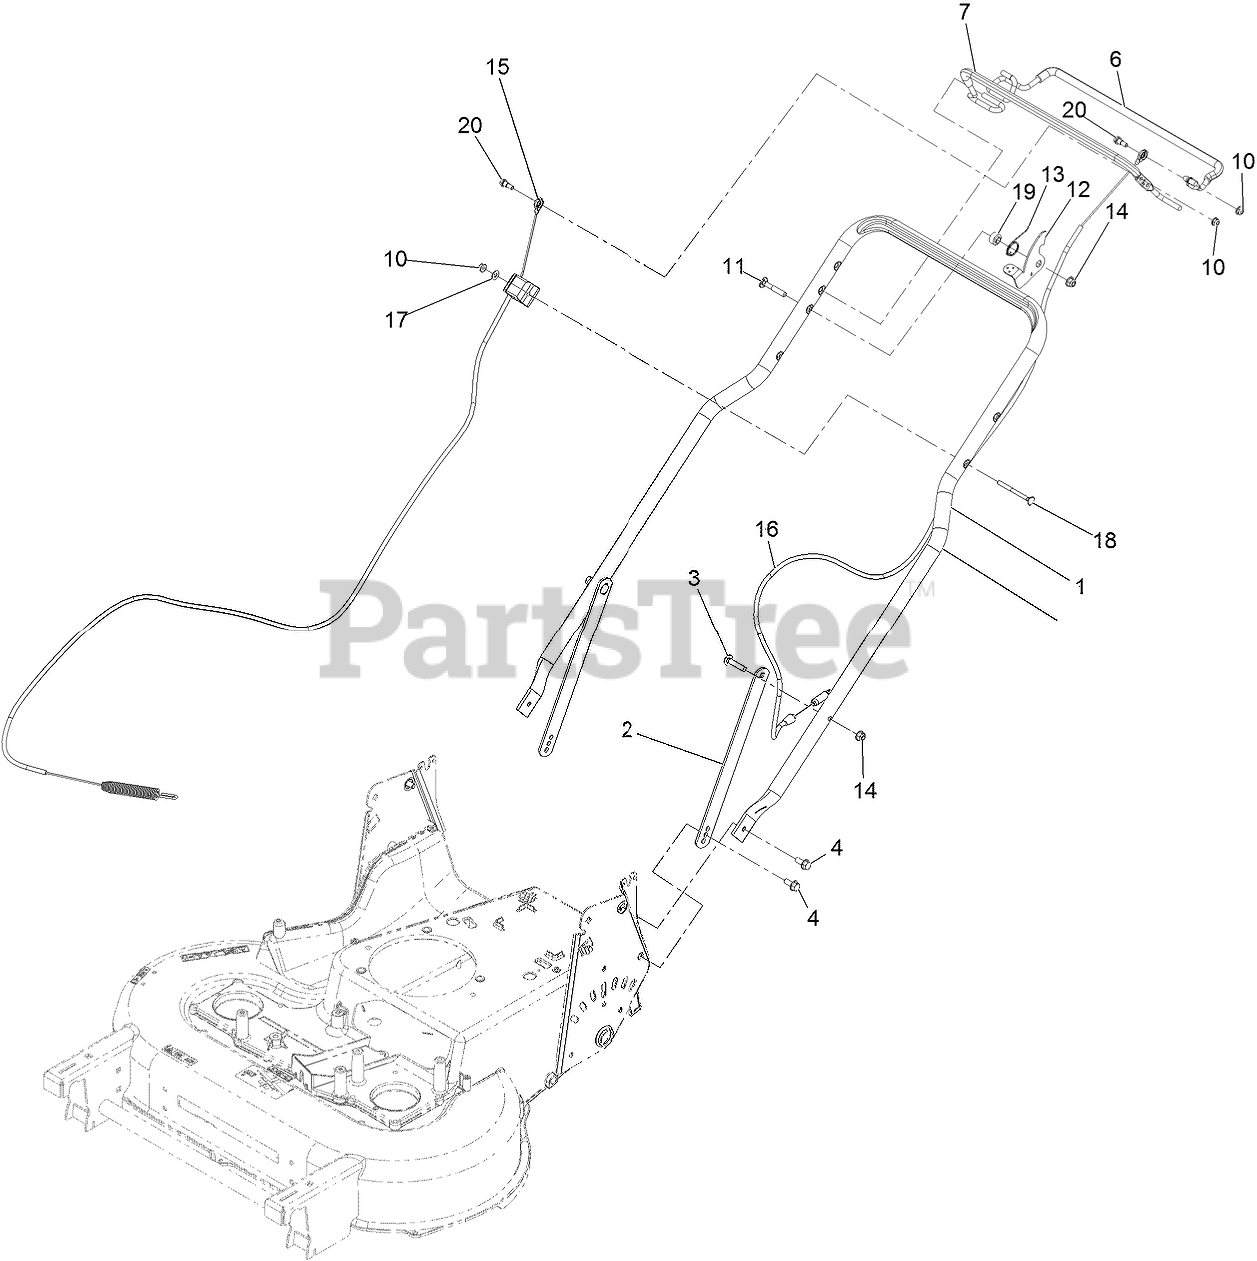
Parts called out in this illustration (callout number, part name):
2	SUPPORT-HANDLE
3	BOLT-CARR
4	SCREW-HHF
6	BAIL-TRACTION, COATED
7	BAIL-BBC, COATED
12	LEVER-BBC
13	SPRING-LEVER, BBC
14	NUT-HF, NI
15	CABLE-BBC
16	CABLE-TRACTION
17	Washer-Flat
18	SCREW-HANDLE
19	BUSHING-STEPPED
20	BOLT-SHOULDER
